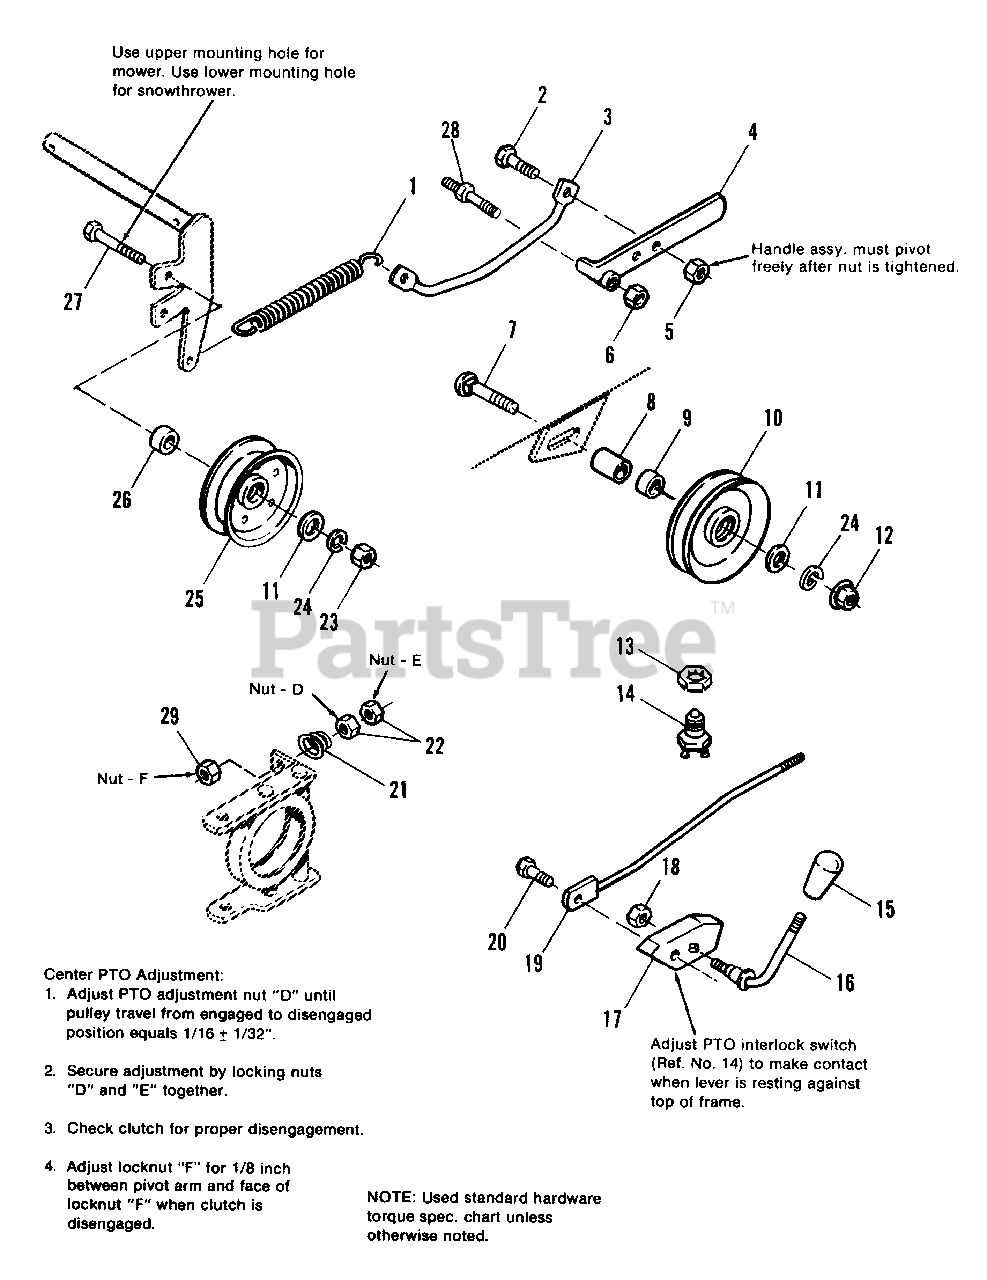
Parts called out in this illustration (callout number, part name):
1	SPRING, Tension
2	CAPSCREW, Hex Hd., 5/16-18 x 3/4
3	ROD, Tension
4	HANDLE ASSY.
5	LOCKNUT, Hex, 5/16-18
6	LOCKNUT, Hex, 7/16-14
7	BOLT, Carriage, 3/8-16 x 1-3/4
10	PULLEY ASSY., w/Bearings
11	WASHER, Plain, 3/8
12	LOCKNUT, Hex, Flange, 3/8-16
13	NUT, Pal
14	SWITCH, Interlock
15	KNOB
16	HANDLE, PTO, Clutch
18	LOCKNUT, Hex, 3/8-16
19	ROD ASSY., Control
20	CAPSCREW, Special
22	NUT, Hex, Full, 5/16-18
23	NUT, Hex, Full, 3/8-16
24	LOCKWASHER, 3/8
25	PULLEY, Idler
27	CAPSCREW, Hex Hd., 3/8-16 x 2
29	LOCKNUT, Hex, Jam, Cntr., 5/16-18
